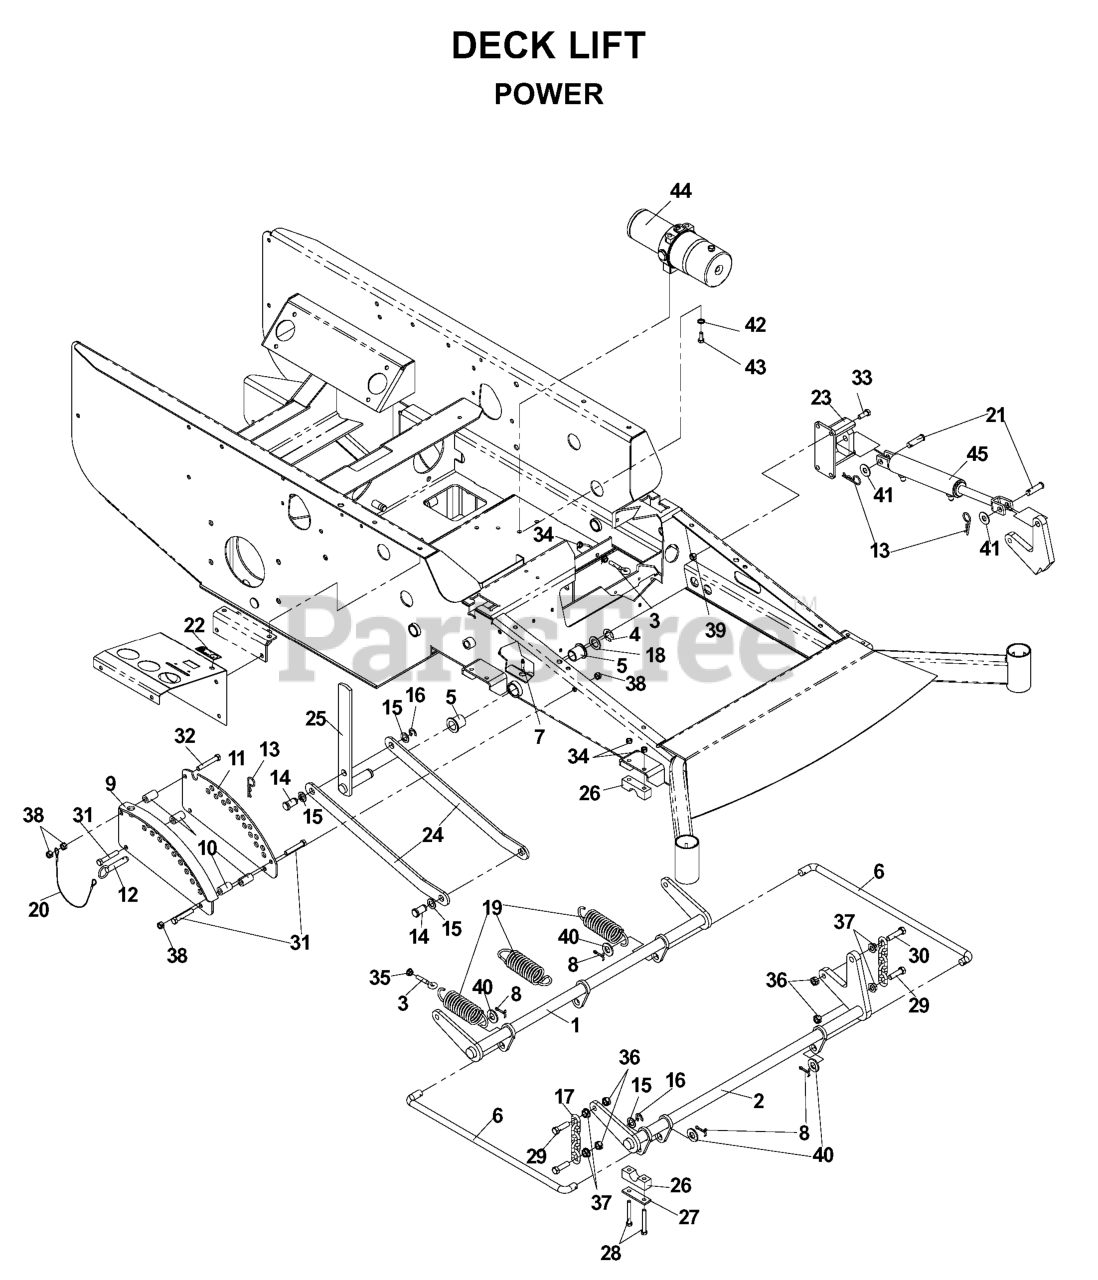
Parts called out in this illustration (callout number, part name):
1	LIFT SHAFT
2	LIFT SHAFT WELDMT FRONT
3	EYEBOLT, RH
4	E-RING 7/8
5	BUSHING, FLANGED
6	CONNECTING LINK
7	GREASE ZERK LONG
8	COTTER PIN
9	ADJ. PLATE WLDMNT
10	DECK LIFT SPACER
11	ADJ. PLATE PAINTED
13	HAIRPIN #4
14	CLEVIS PIN
16	E-RING 5/8
17	LIFT CHAIN
18	BSHG .875 X 1.375 X .074 ZD
19	DECK LIFT SPRING
21	CLEVIS PIN 1/2 X 3/4
22	DECAL, LIFT SWITCH
23	CYLINDER MTG WLDMT
24	LIFT LINKAGE,PAINTED
25	LIFT LEVER
26	PILLOW BLOCK
27	REINFORCEMENT BAR
28	BOLT 5/16C X 2 1/2
29	HCS 7/16C X 1 1/2
30	HCS 7/16 - 14 X 1 3/4
31	HCS 3/8C X 2 1/4
32	HCS 3/8C X 2 1/2
33	HCS 3/8-16X1.GRD.5.ZD
34	NUT 5/16C CENTERLOCK
35	NUT 5/16C WHIZ
36	NUT 7/16C CENTERLOCK
37	NUT 7/16C WHIZ
38	NUT 3/8C CENTERBLOCK
39	NUT 3/8-16 NYLOC
40	WASHER 5/8 FLAT
41	WASHER 1/2 FLAT
42	SLW 3/8 STD
43	SCREW 3/8C X 3/4 HEX CAP
44	HYDRAULIC POWER UNIT
45	HYDRAULIC CYLINDER
539107869	SWITCH BOOT
539107871	HYDRAULIC HOSE ASSY
